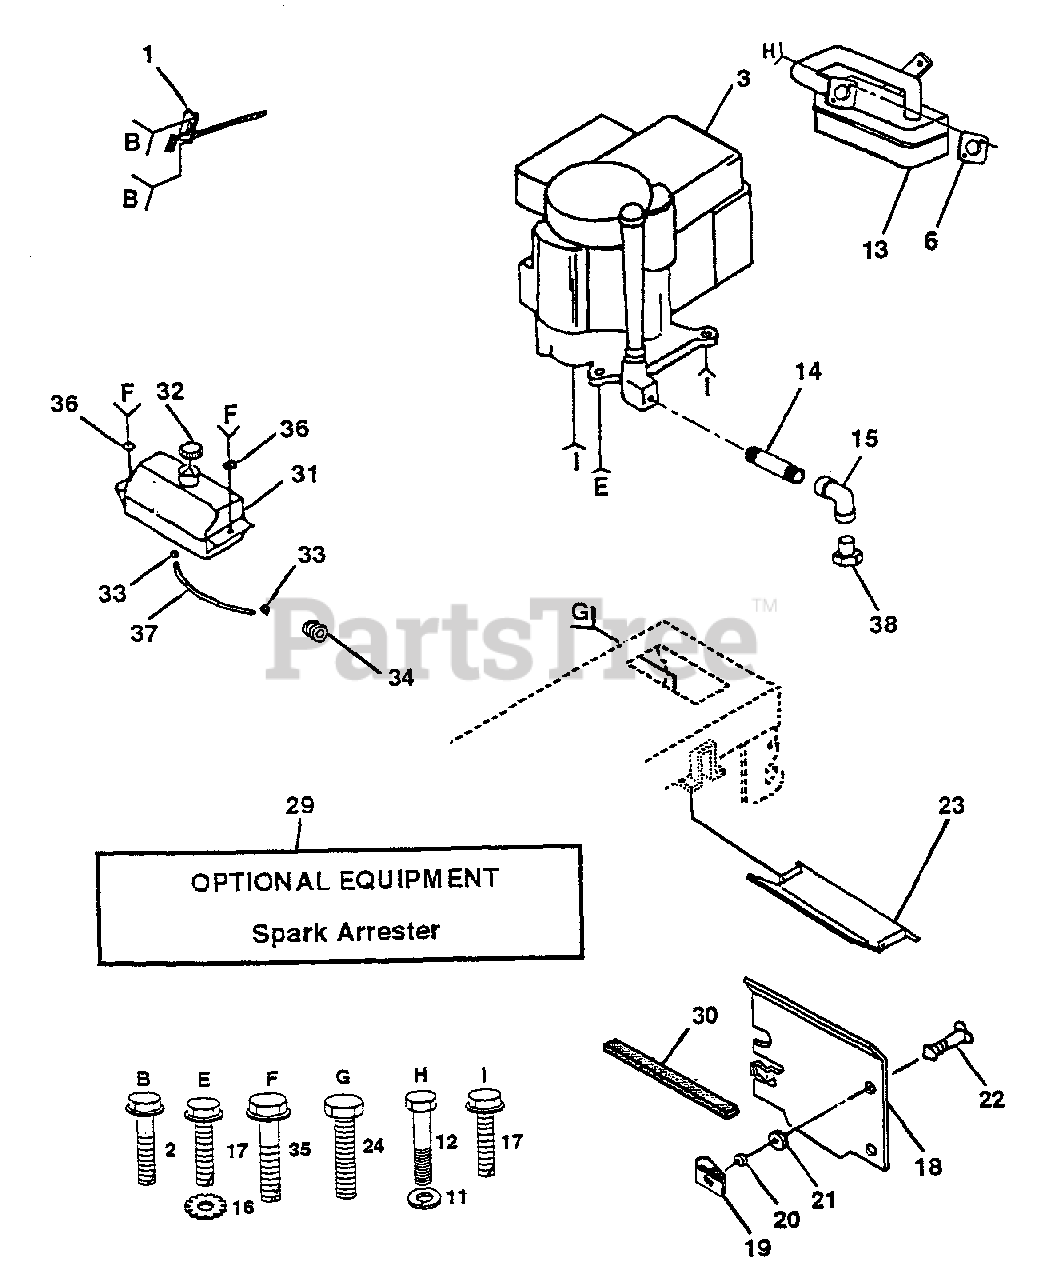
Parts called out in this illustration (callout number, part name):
1	Control Th/ch 23 5 LH Flag
2	Screw Hex Thd Cut 1/4-20x5/8 T
3	Engine B&S 12.5 ICQ IVT Dual
6	Gasket Eng 1 313 Id Tin Plated
11	Washer Lock Hvy Hlcl Spr 5/16
12	Screw Hexhd Cap 5/16-18x 3/4
13	Muffler LT B&S 12/12.5/13HP
14	Nipple Pipe 3/8 Npt X 3"
15	Elbow Std 90 Degree 3/8-18 Npt
16	Washer Lock Ext Tooth 3/8
17	Screw Thdrol 3/8-16x1-1/4 TYTT
18	Shield Heat Lt
19	Receptacle 1/4 turn
20	Retainer 1/4 turn
21	Washer 9/32 x 5/8 x 16 Ga.
22	Stud 1/4 turn
23	Shield-Heat Browning LT/YT
24	Screw Tap Hex #10-24unc X 1/2
29	Kit Spark Arrestor (Flat Scm)
30	Pinch Weld Hood Black
31	Tank Fuel Front 2 00
32	Cap Asm Fuel W/sym Vented
33	Clamp Hose Black
34	Bushing Snap Nyl Blk Fuel Line
35	Screw Hexwsh Thdrol 1/4-20x3/4
36	Washer 9/32 X 7/8 X 16 Ga
37	Line Fuel 20"
38	Plug Oil Drain
